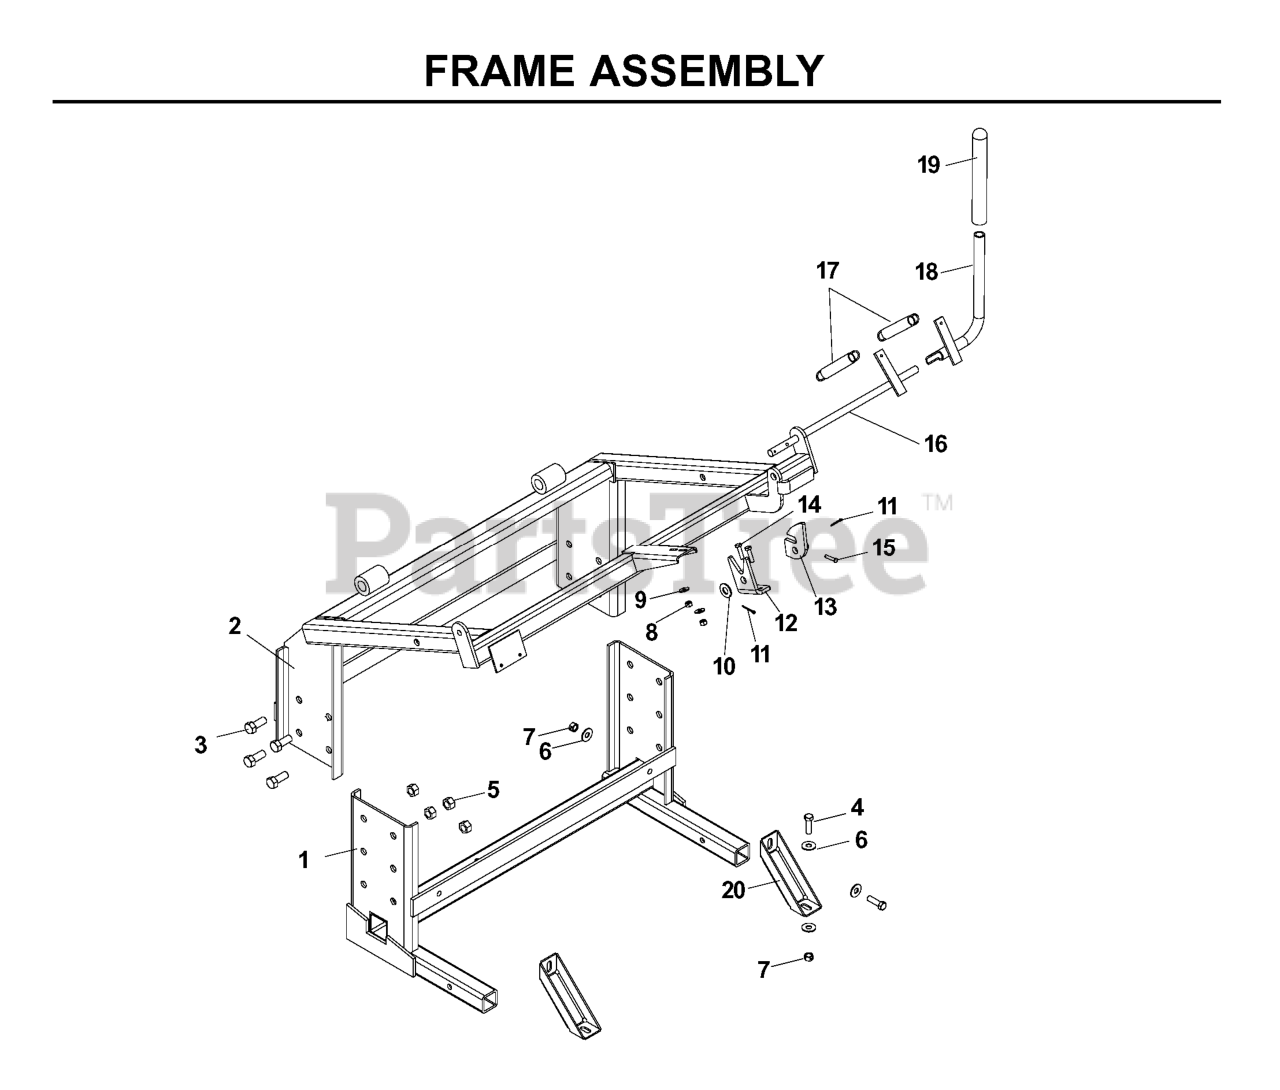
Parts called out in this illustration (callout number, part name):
1	LOWER FRAME
2	UPPER FRAME
3	BOLT 1/2 X 1.25
4	BOLT 3/8 X 1.25
5	NUT 1/2 NYLOC
6	FLAT WASHER 3/8
7	NUT 3/8 NYLOC
8	Nut, Hex, Nylon Lock, 1/4"-20
9	WASHER, 1/4
10	FLAT WASHER 1/2"
11	PIN, COTTER, 3/32 X 3/4
12	LATCH BASE
13	WELDMENT, LATCH CATCH BLK
14	BOLT, 1/4-28 X 1
15	PIN, CLEVIS, 3/16 X 1
17	SPRING
18	RELEASE LEVER
19	GRIP
20	HITCH BRACKET
